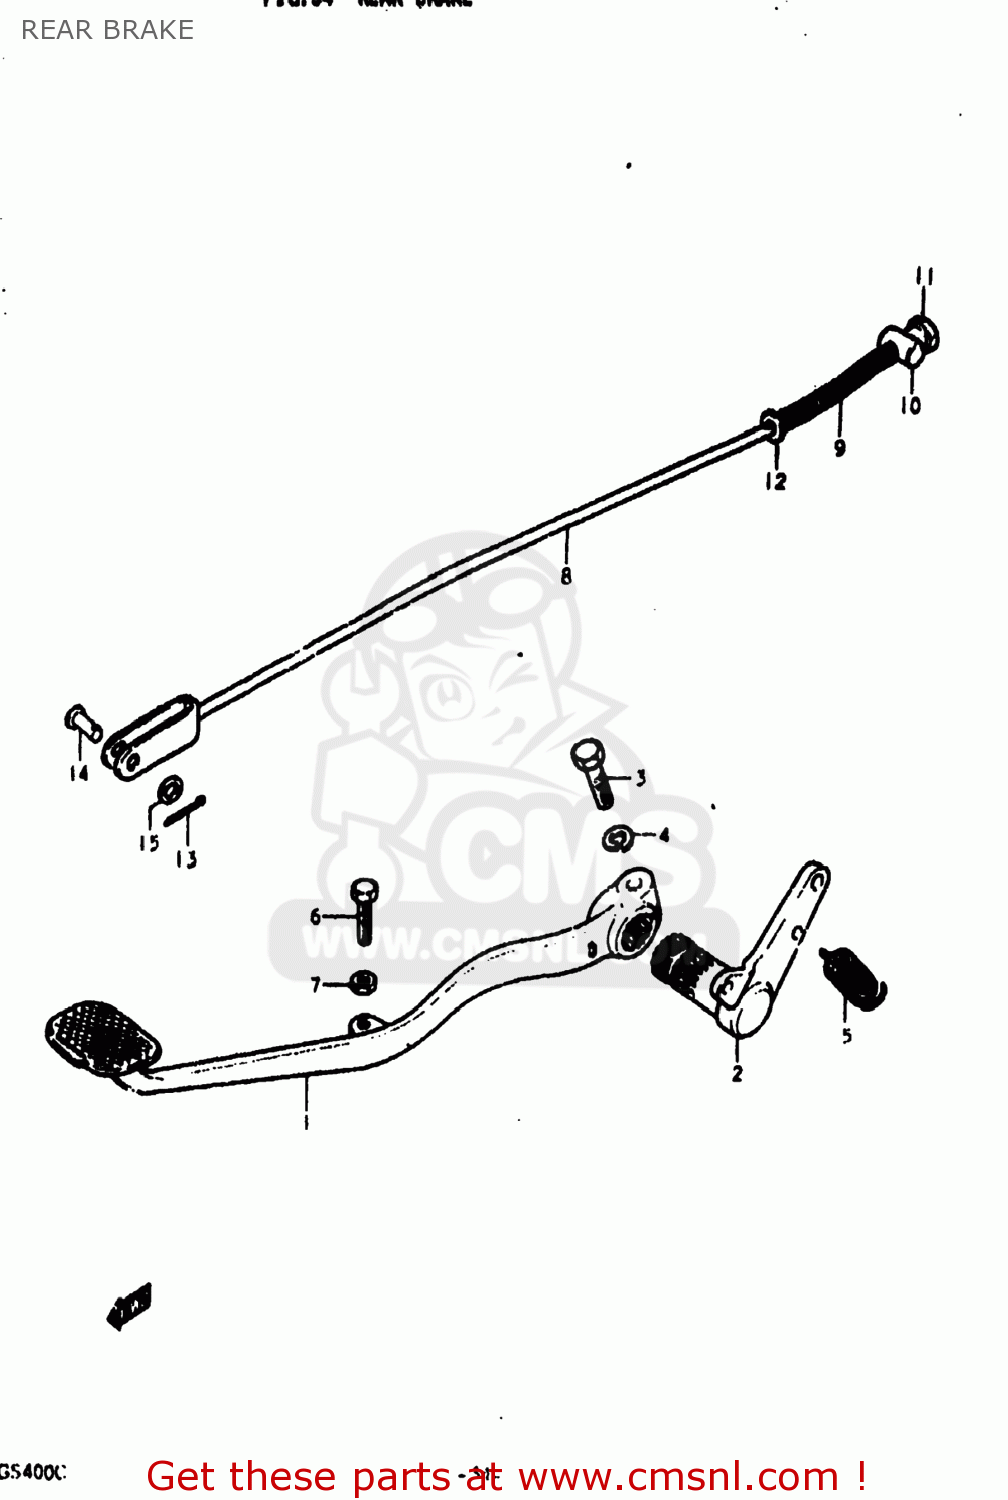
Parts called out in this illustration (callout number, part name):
1	PEDAL,BRAKE
2	ARM,BRAKE PEDAL ROD
3	BOLT
4	LOCK WASHER
5	SPRING
6	BOLT
7	NUT
8	ROD ASSEMBLY,REAR BRAKE
9	SPRING
10	PIN
11	NUT
12	WASHER
13	PIN 20X20
14	PIN(L:13.5)
15	WASHER
